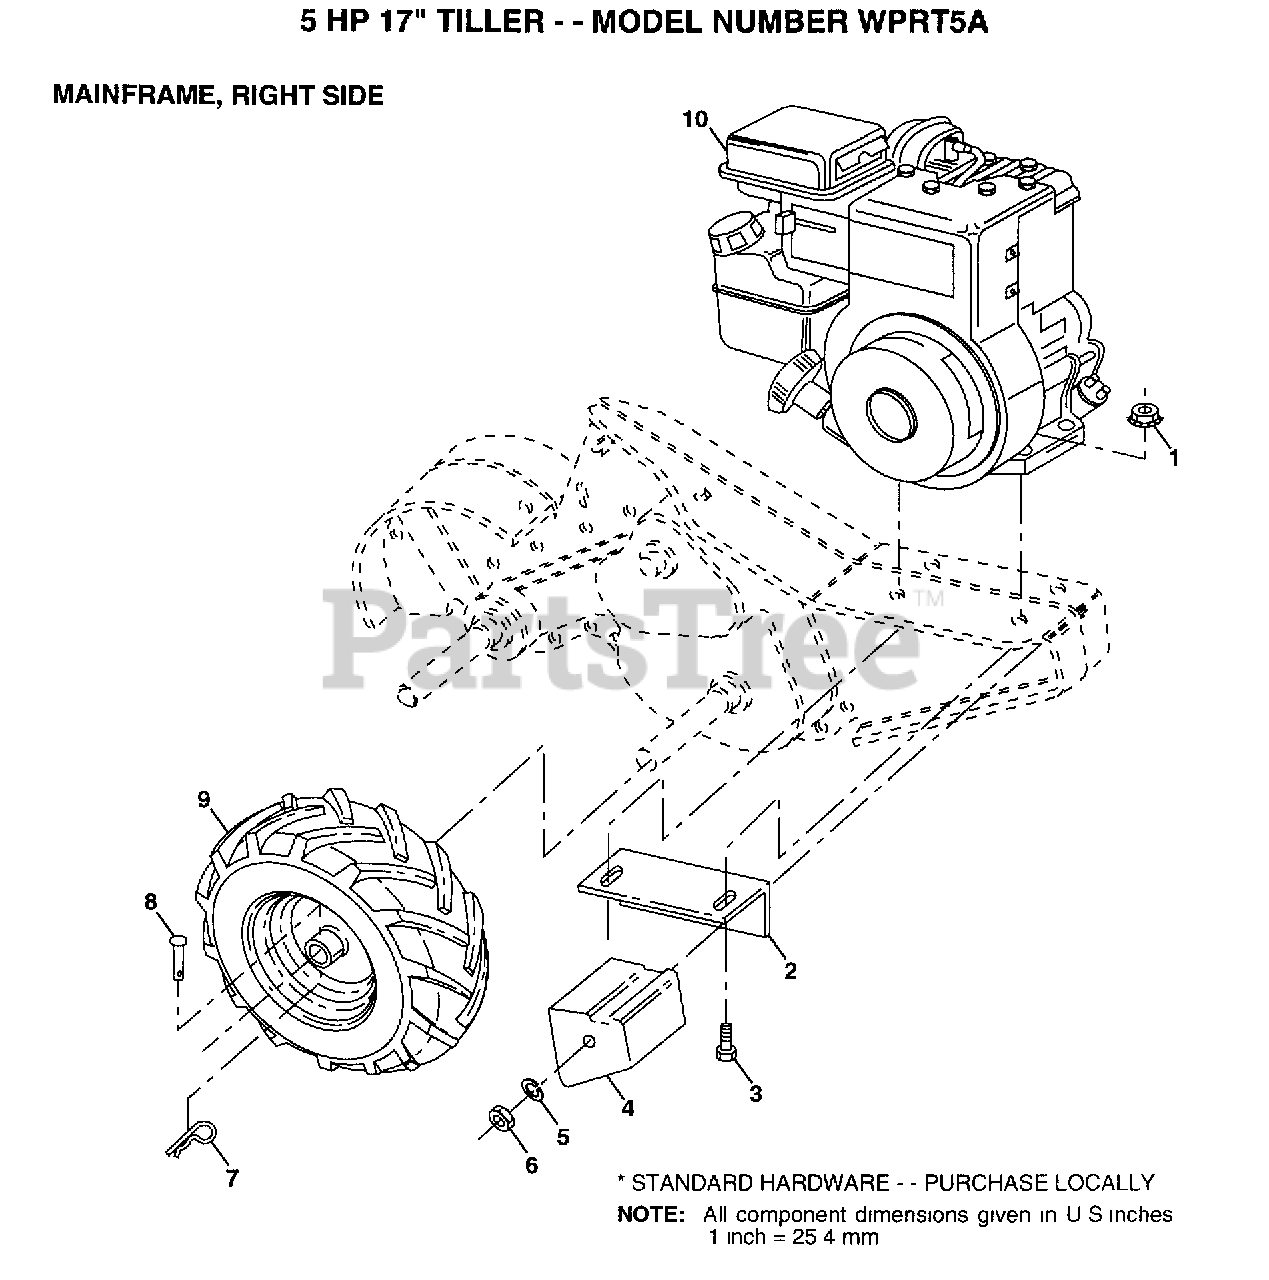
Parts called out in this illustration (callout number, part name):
2	BRACKET RH CRT
3	BOLT.HEX.5/16-1.5
4	COUNTERWEIGHT CRT
5	LOCKWASHER
6	NUT.HEX.3/8-16UNC
7	RETAINER M
8	RIVET.DRILL.1.75
9	TIRE.CHV.13X5.0-6
